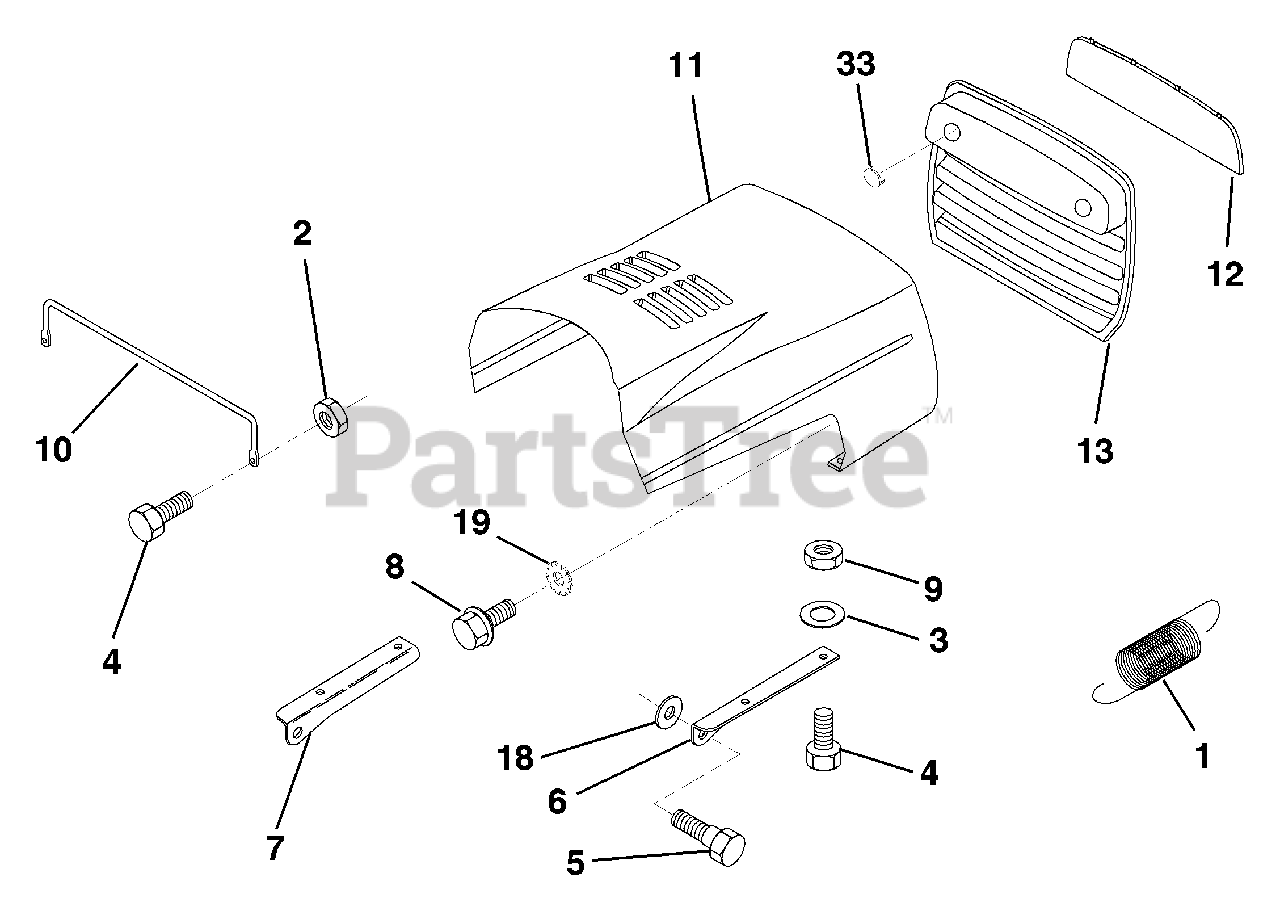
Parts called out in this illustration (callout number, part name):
1	Extension, Spring
2	Nut, Hex, Keps 1/4-20
3	Washer, 9/32 x 7/8 x 16 Ga.
4	Bolt, Hex Fin 1/4-20 x 3/4 Gr. 5
5	Bolt, Shoulder
6	Bracket, Hood R. H.
7	Bracket, Hood L.H.
8	Screw Sltd. Hex Hd W/PL Washer
9	Nut Lock W/Insert 1/4-20 UNC
10	Brace, Hood
11	Hood
12	Lens Clear Bar
18	Washer 11/32 x 11/16 x 16 Ga.
19	Washer Lock 1/4 Int/Ext Tooth
33	Plug socket light
